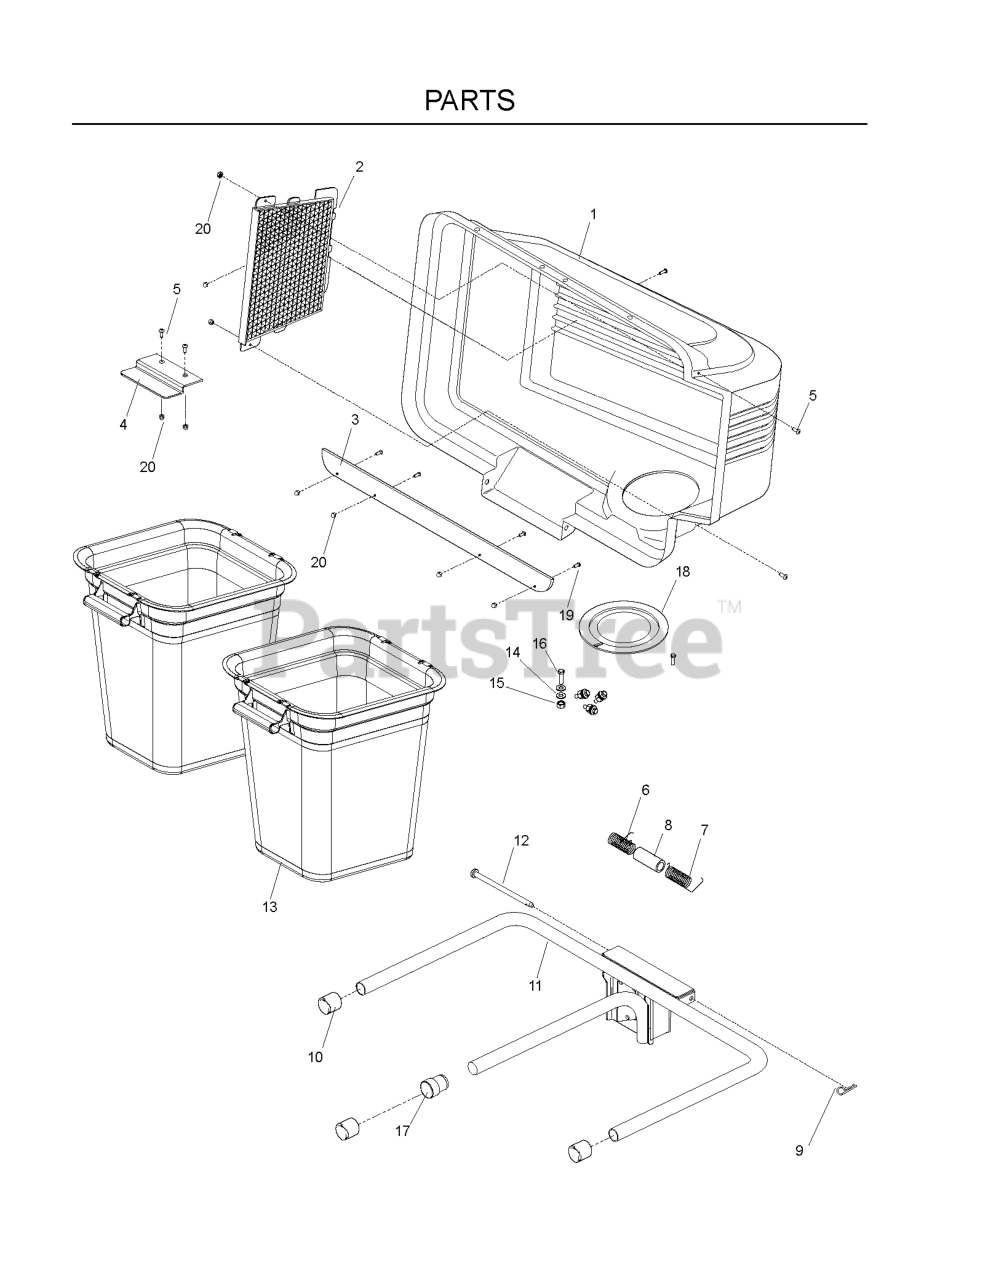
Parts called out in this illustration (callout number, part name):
1	HOOD ASM
2	COVER SCREEN
3	STRIP.REINFORCE.BAGGER.2BIN.BL
4	LATCH CER38
5	SCREW #10-24 X 5/8
6	SPRING COVER LH
7	SPRING COVER RH
8	SPACER.COVER.BAGGER
9	RETAINER SPRING
10	PLUG, TUBING END
11	FRAME.ASM.BAGGER.2BIN.QC42B
12	HINGE PIN
13	CONTAINER BAG, SOFT
14	WASHER #10
15	NUT 10-24 NYLOC
16	SCREW 10-24 X 3/4
17	SPACER PLUG, BAGGER
18	GASKET.COVER.BAGGER
19	SCREW
20	NUT 10-24 ACORN ZD
